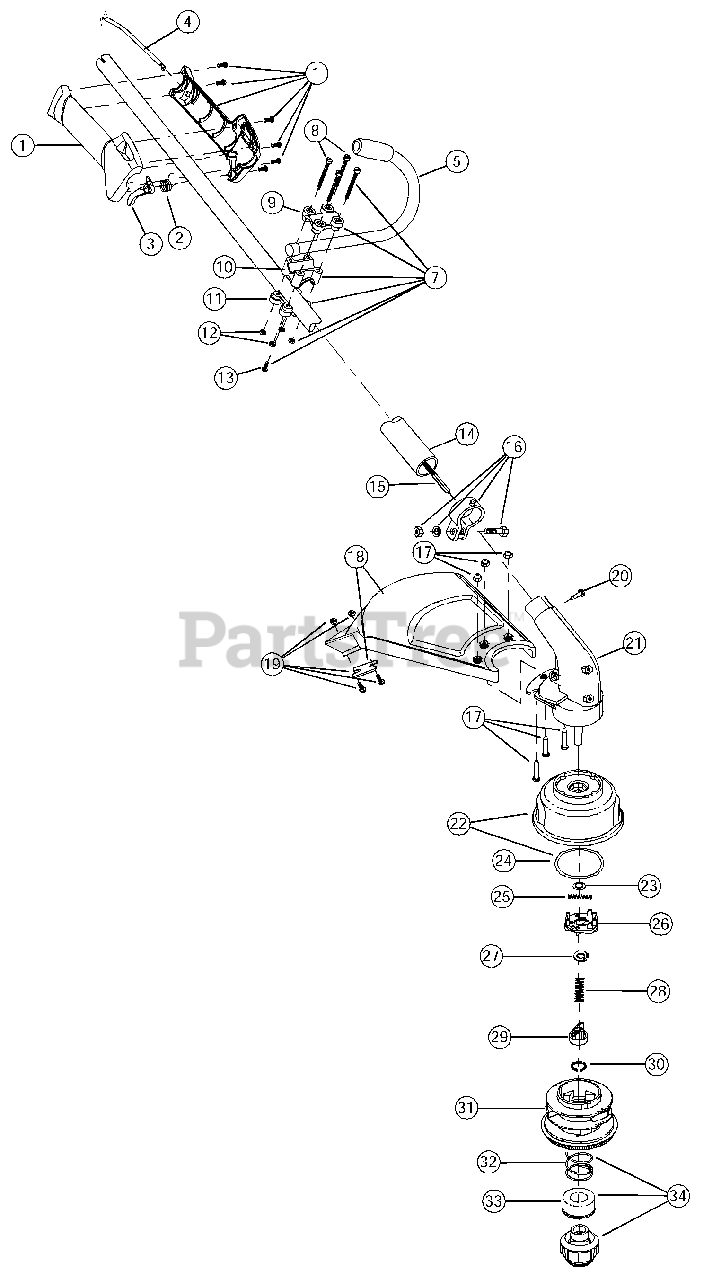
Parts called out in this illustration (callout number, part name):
1	Throttle Housing and Trigger Assembly
2	Throttle Trigger Spring
3	Throttle Trigger
4	Throttle Cable
5	J-Handle Assembly
7	Handle Bracket Assembly
9	Upper Handle Clamp
10	Middle Handle Clamp
11	Lower Handle Clamp
13	Anti-Rotation Screw
14	Drive Shaft Housing Assembly
15	Flexible Drive Shaft
16	Lower Clamp Assembly
17	Guard Mounting Screw Assembly
18	Guard & Blade Assembly
19	Blade Assembly
20	Anti-Rotation Screw
21	Gearbox Assembly
22	Outer Spool & Eyelet Assembly
23	Retainer
24	Thrust Washer
25	Small Spring
26	Slider
29	Plunger
31	Inner Reel
32	Large Spring
33	Foam Seal & Washer
34	Bumb Head Knob Assembly
